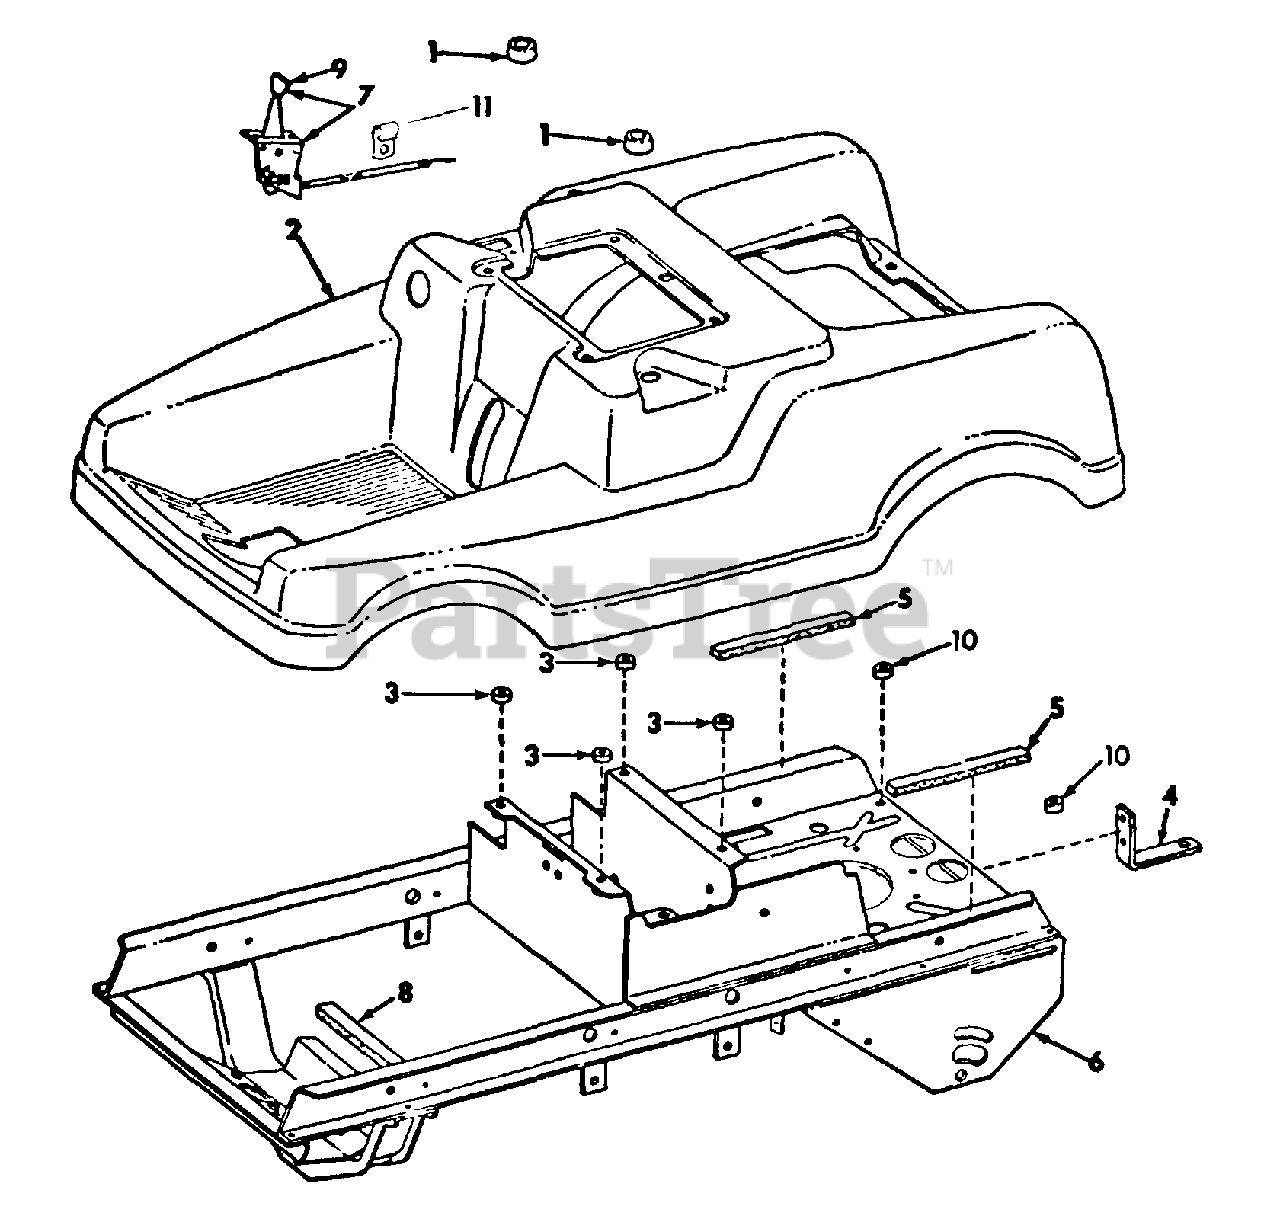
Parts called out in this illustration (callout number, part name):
1	BUMPER, SEAT SUPPORT REAR
2	BODY W/PLUG, IH-432485 AND PLUG, IH-432580, RIDING MOWER
3	SPACER, BODY MOUNTING
4	ANGLE, DRAWBAR
5	SEAL, PRESSURIZED
6	FRAME W/PRODUCT GRAPHIC, IH-120391-C1 ASSY, MAIN
7	CONTROL, THROTTLE
8	SEAL, PRESS FRT REST
9	KNOB, THROTTLE CONCORDE
10	SPACER, BODY MTG REAR
11	CLIP, HOOK
